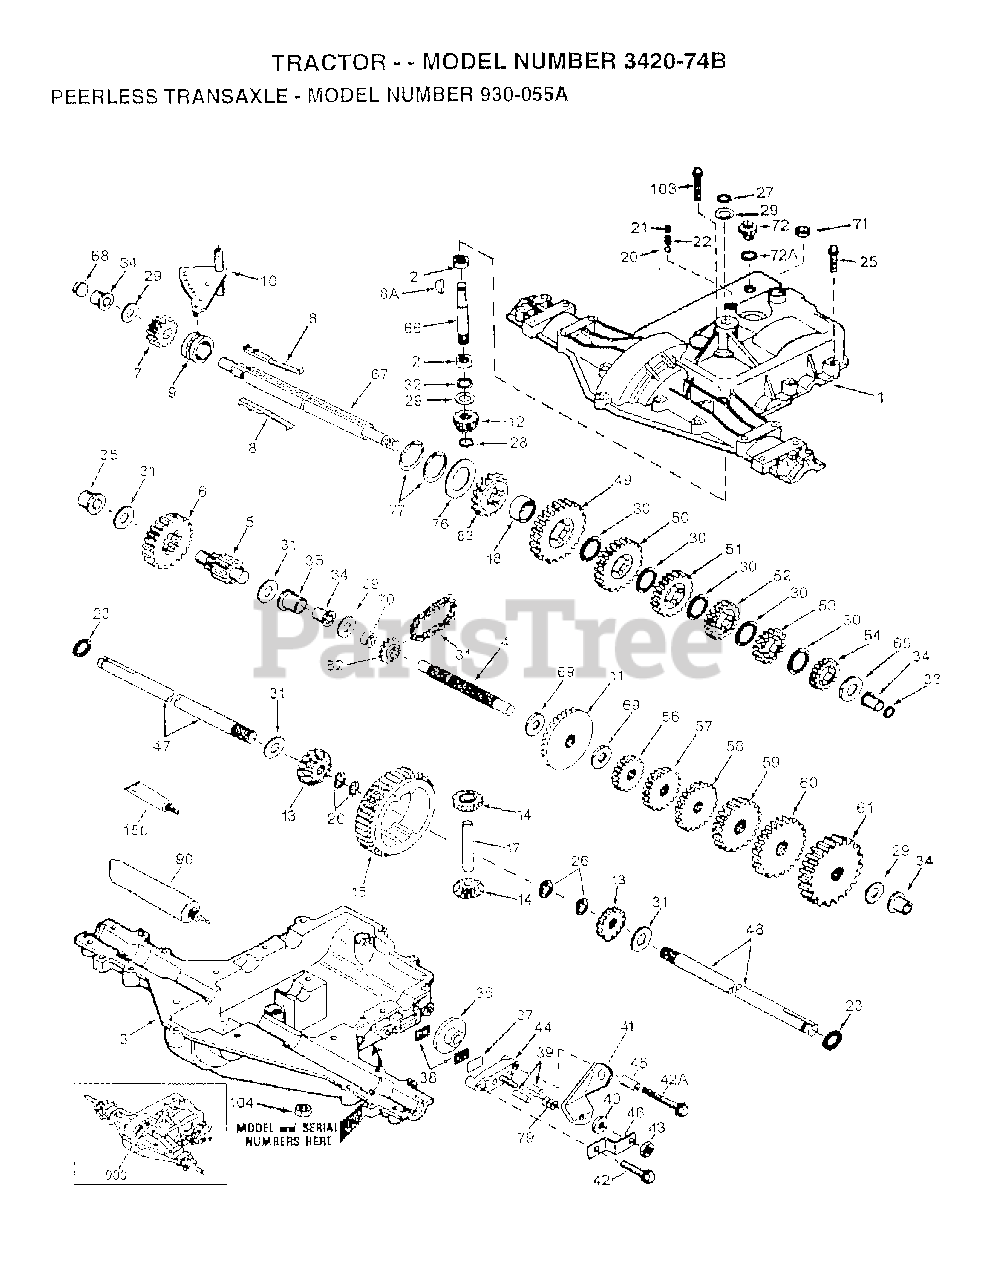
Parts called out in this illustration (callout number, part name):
1	Poulan TBD
3	Poulan TBD
5	Poulan TBD
8	Poulan TBD
12	Poulan TBD
34	Poulan TBD
35	Poulan TBD
51	Poulan TBD
52	Poulan TBD
53	Poulan TBD
58	Poulan TBD
59	Poulan TBD
60	Poulan TBD
67	Poulan TBD
68	Poulan TBD
90	Poulan TBD
